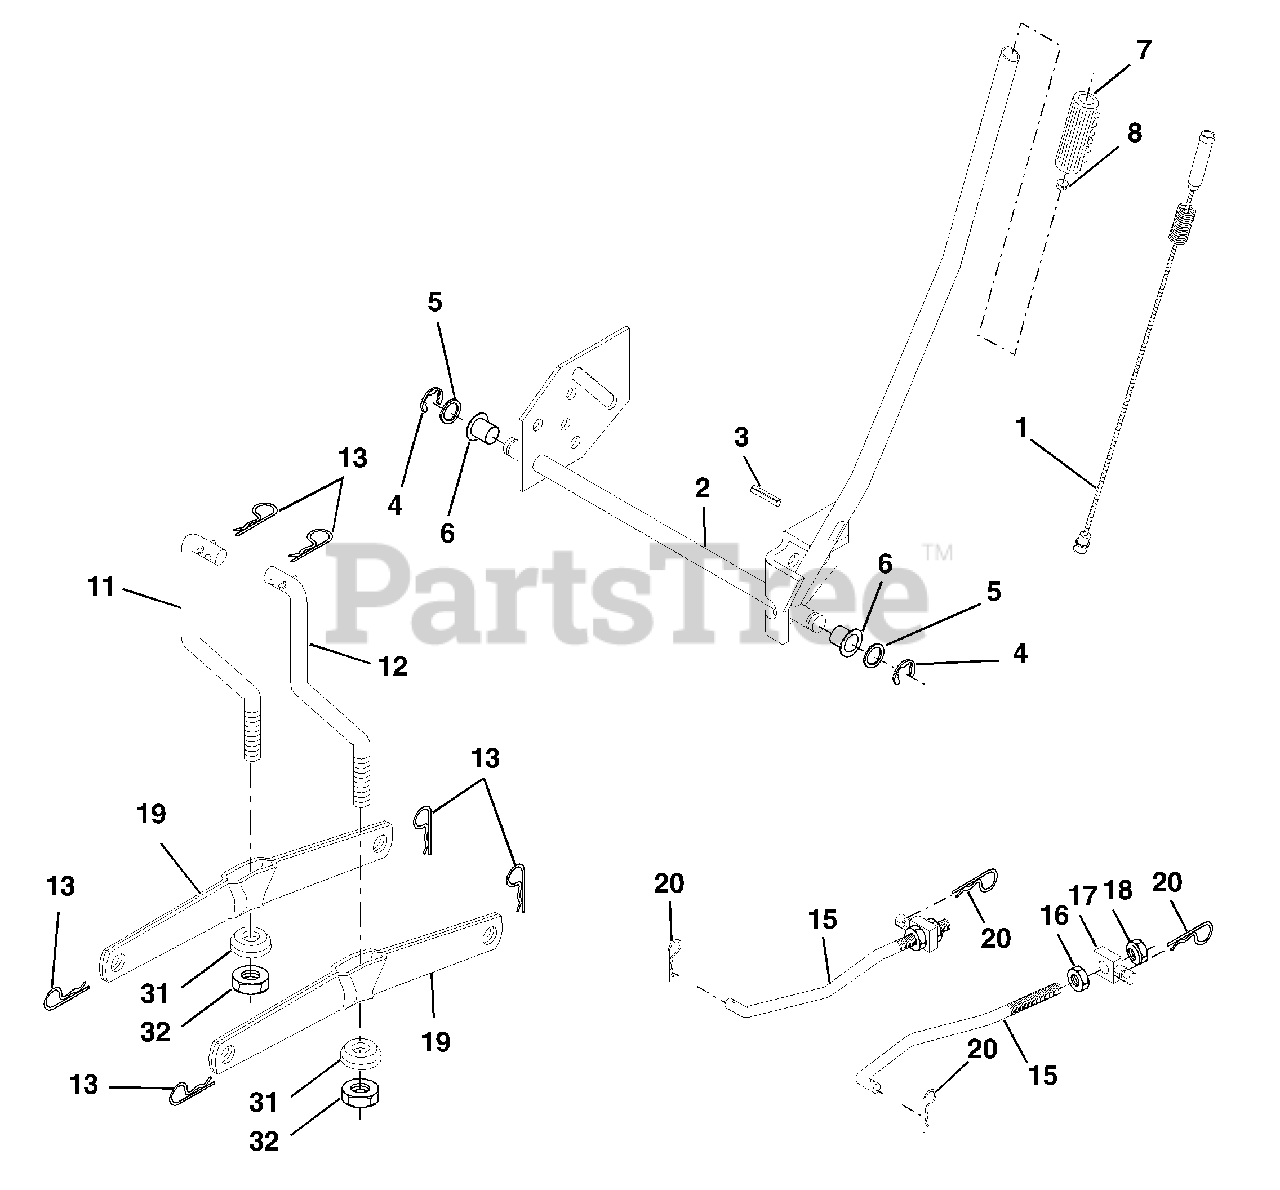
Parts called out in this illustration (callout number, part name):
1	Wire Asm Inner/Sprg w/plunger
2	Shaft Asm Lift RH
3	Pin Groove 1 500 Zinc
4	E Ring #5133-62
5	Washer 21/32 X 1 X 21 Ga
6	Bearing Nylon Blk 629 Id
7	Grip Handle Bicycle Matte Blk
8	Button Plunger Black
11	Link Lift LH Fixed Length
12	Link Lift RH Fixed Length
13	Retainer Spring
15	Link Front
16	Nut Jam Hex 1/2-13 Unc
17	Trunnion Blk Zinc
18	Nut Lockw/Wsh 1/2-13 Unc
19	Arm Suspension Rear
20	Retainer,Spring
31	Bearing Pvt Lift
32	Nut Crownlock 3/8-24
